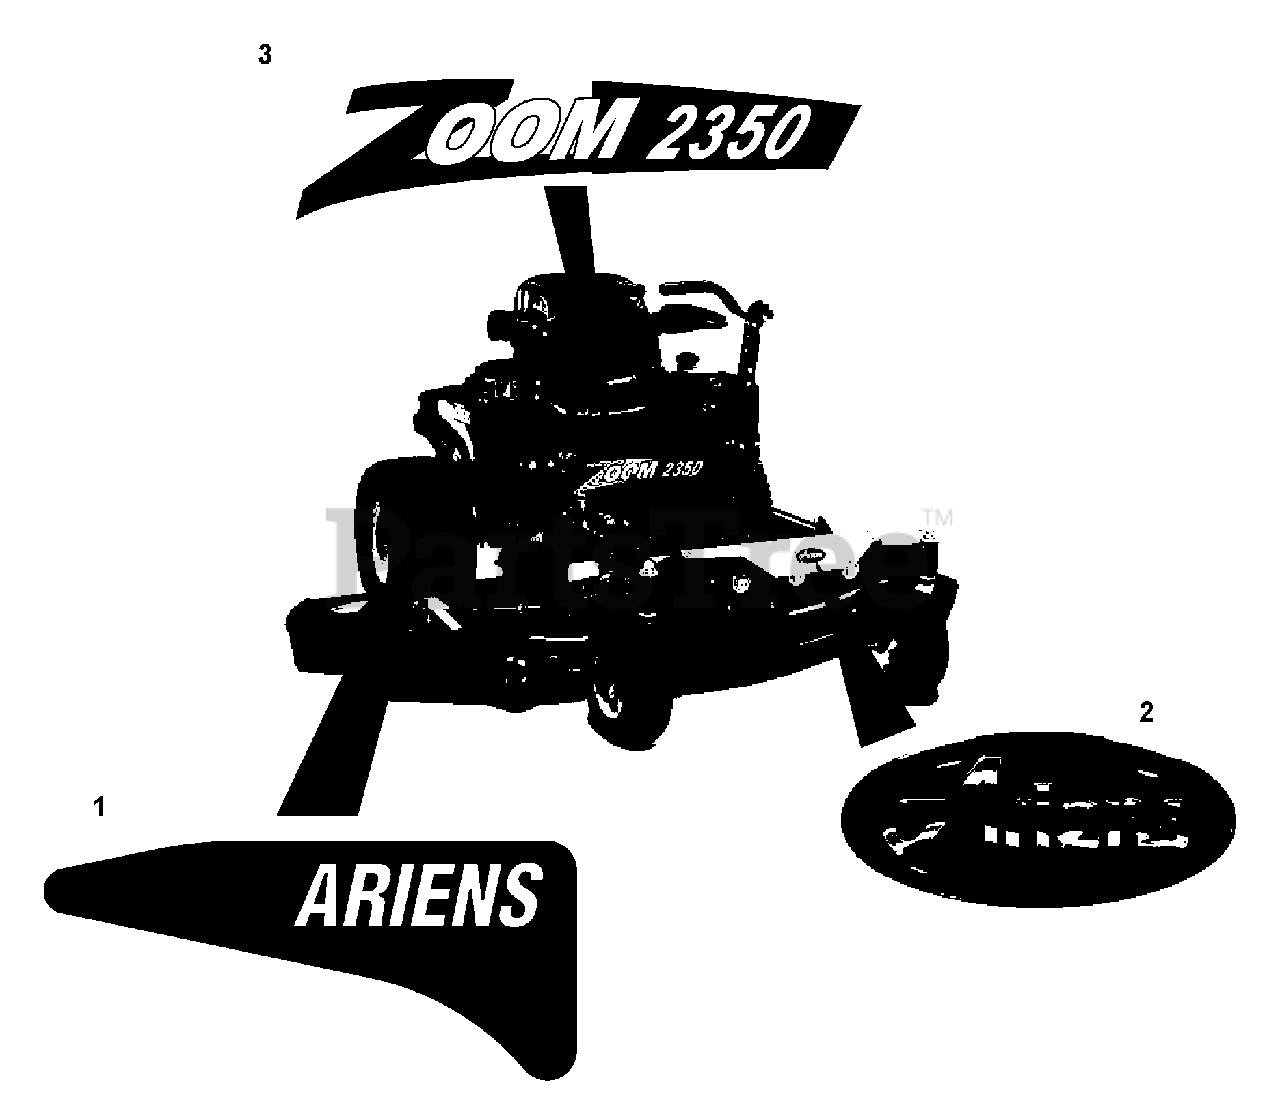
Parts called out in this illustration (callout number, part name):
1	DECAL, RH ARIENS ZOOM TANK
2	DECAL-ARIENS JEWEL
3	DECAL, 2350 ZOOM
